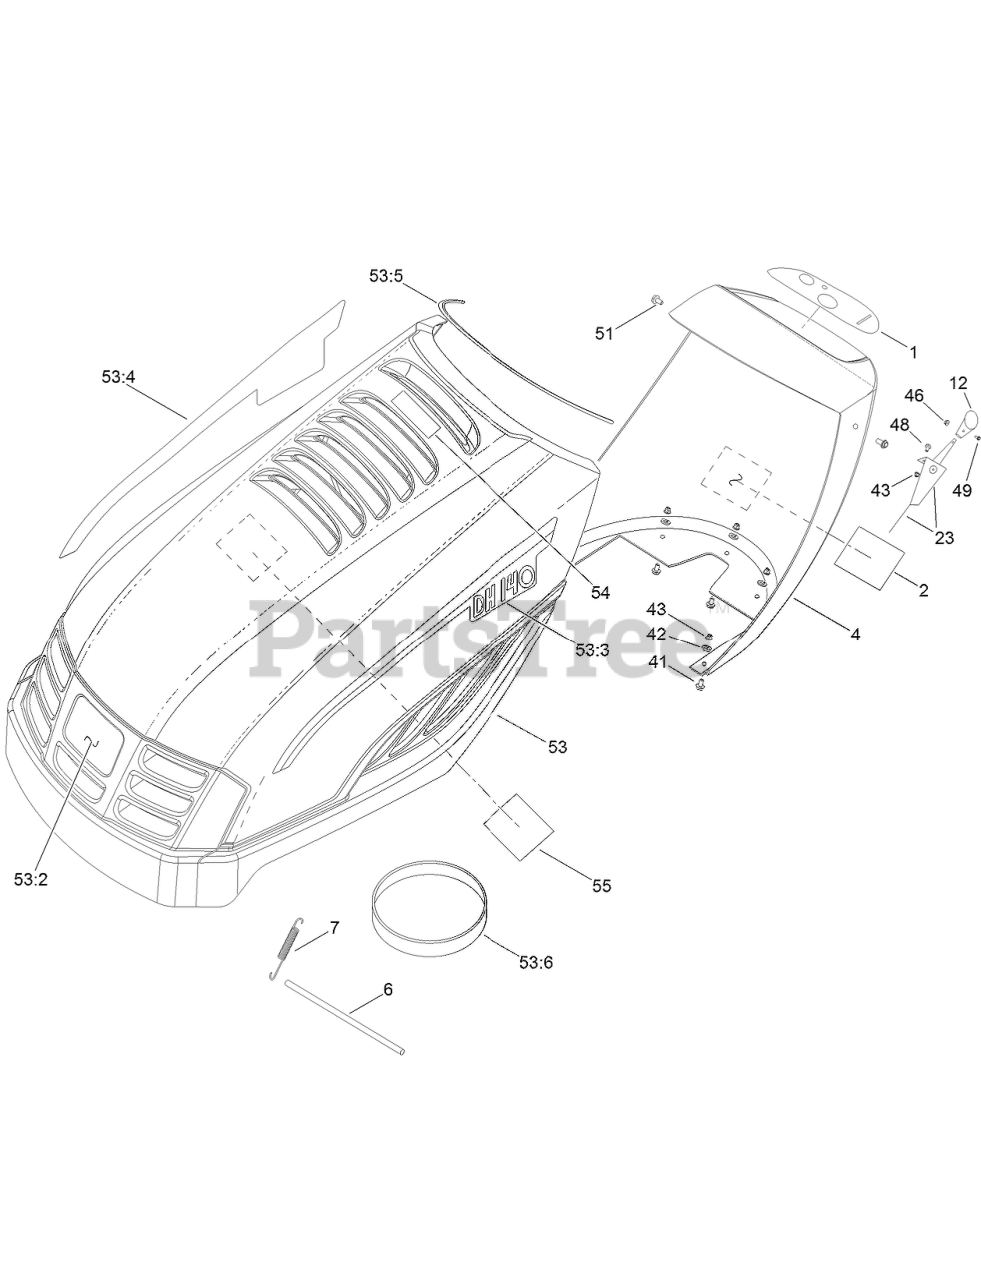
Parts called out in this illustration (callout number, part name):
1	DECAL-PANEL
2	DECAL-INSTRUCTIONS, OPERATING
4	PANEL-DASH
6	BAR-SAFETY
7	SPRING-HOOD
12	KNOB-THROTTLE/CHOKE
23	CABLE-THROTTLE/CHOKE
41	SCREW-HEX
42	WASHER-FLAT
43	NUT-LOCK
46	NUT-HEX
48	SCREW-FLAT HEAD
53	HOOD ASM
53:3	DECAL-DH 140 (LH)
53:4	DECAL-DH 140 (RH)
53:5	RUBBER-PURL
53:6	GASKET-FOAM
54	DECAL-WARNING, HOOD
55	DECAL-DANGER
